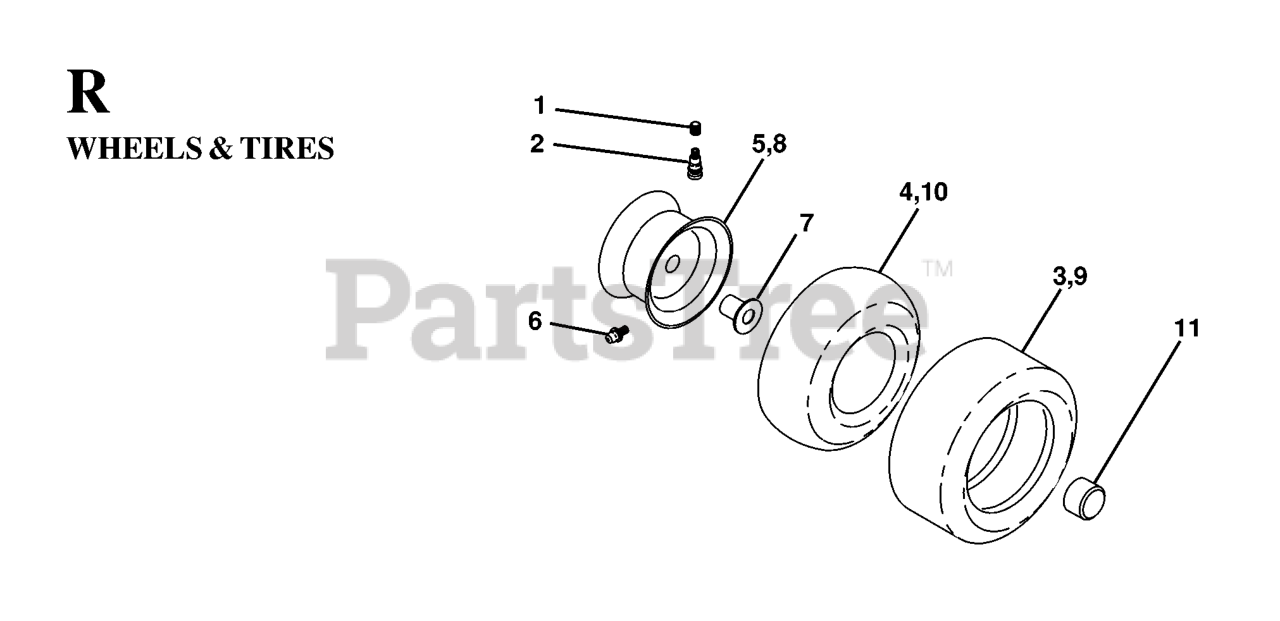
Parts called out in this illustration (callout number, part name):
2	VALVE STEM LT
3	TIRE HEAVY DUTY
4	TUBE.5.3/4.5/6
5	RIM ASM 6" FRONT SILVER
6	FITTING LT
7	BEARING T
8	RIM ASM 8" REAR SILVER
9	TIRE.TS.20X10-8
10	TUBE
11	CAP.HUB.FRONT.LT.BLACK
